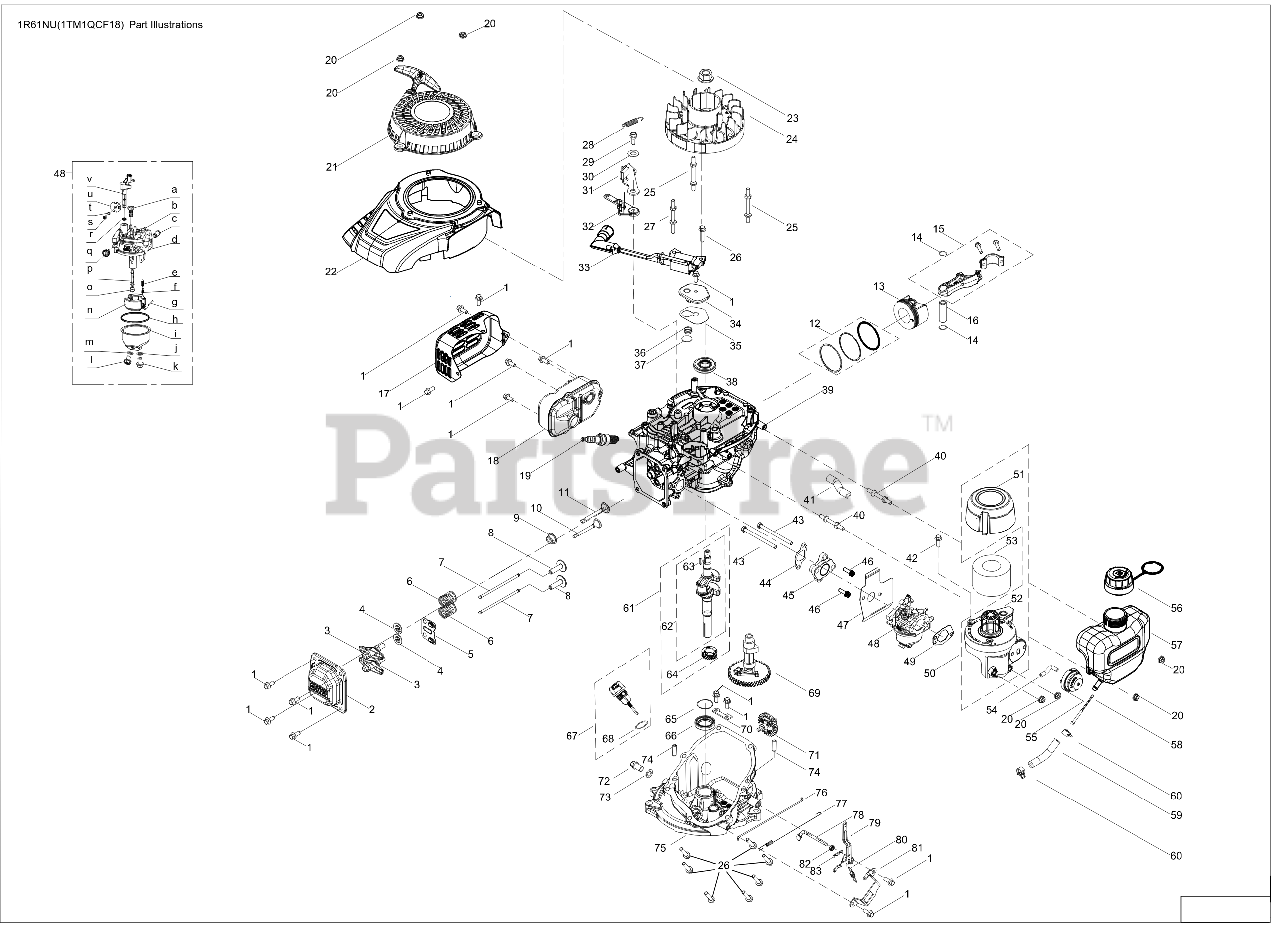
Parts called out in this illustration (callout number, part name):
1	BOLT M6-1 x 14 GR8.8
2	VALVE COVER
3	ROCKER ARM ASSEMBLY
4	VALVE SPRING RETAINER
5	PUSH ROD GUIDE
6	VALVE SPRING
7	PUSH ROD GUIDE
8	TAPPET (LIFTER)
9	INTAKE VALVE SEAL
10	EXHAUST VALVE
11	INTAKE VALVE
12	PISTON RING SET
13	PISTON
14	SNAP RING-PISTON PIN
15	CONNECTING ROD ASSEMBLY
16	PISTON PIN
17	MUFFLER GUARD
18	MUFFLER
19	SPARK PLUG
21	STARTER RECOIL ASSEMBLY
22	SHROUD ASSEMBLY
23	FLYWHEEL NUT
24	FLYWHEEL
25	STUD M6 x 75
26	BOLT M6-1 x 25 GR8.8
27	STUD M6 x 73
28	ENGINE BRAKE SPRING
29	ENGINE BRAKE PIN M6-1.0 MM
30	FLAT WASHER 10x20x1.0 MM
31	ENGINE BRAKE ARM
32	ENGINE BRAKE LOWER BRACKET
33	IGNITION COIL
34	BREATHER COVER PLATE
35	BREATHER GASKET
36	BREATHER VALVE SPRING
37	BREATHER VALVE
38	UPPER CRANKSHAFT SEAL
39	CRANKCASE
40	FUEL TANK MOUNTING STUD M6X59.5
41	BREATHER HOSE
42	BOLT M6 x 16
43	BOLT M6X80
44	CARBURETOR INSULATION GASKET
45	CARBURETOR INSULATOR
46	BOLT M6X20
47	CARBURETOR GASKET
48	CARBURETOR ASSEMBLY KM-1R61BA
49	AIR FILTER BASE GASKET
50	AIR FILTER ASSEMBLY
51	AIR FILTER COVER
52	AIR FILTER BASE
53	AIR FILTER - FOAM
54	PRIMER HOSE
55	VENTED PRIMER ASSEMBLY
56	FUEL CAP W/TETHER
58	FUEL FILTER
59	FUEL HOSE
60	HOSE CLAMP
61	CRANKSHAFT ASSEMBLY
62	CRANKSHAFT ASSEMBLY
63	FLYWHEEL KEY
64	CRANKSHAFT TIMING GEAR
65	THRUST WASHER
66	LOWER CRANKSHAFT SEAL
67	DIPSTICK ASSEMBLY
68	DIPSTICK SEAL
69	CAMSHAFT ASSEMBLY
70	GOVERNOR GEAR MOUNTING PLATE
71	GOVERNOR GEAR/SHAFT ASSEMBLY
72	OIL DRAIN PLUG
73	WASHER
74	DOWEL PIN 7X20
75	CRANKCASE COVER
76	THROTTLE LINKAGE
77	THROTTLE LINKAGE SPRING
78	GOVERNOR ARM SHAFT
79	GOVERNOR ARM ASSEMBLY
80	GOVERNOR SPRING
81	COMPONENT BRACKET
82	GOVERNOR SEAL
83	COTTER PIN
